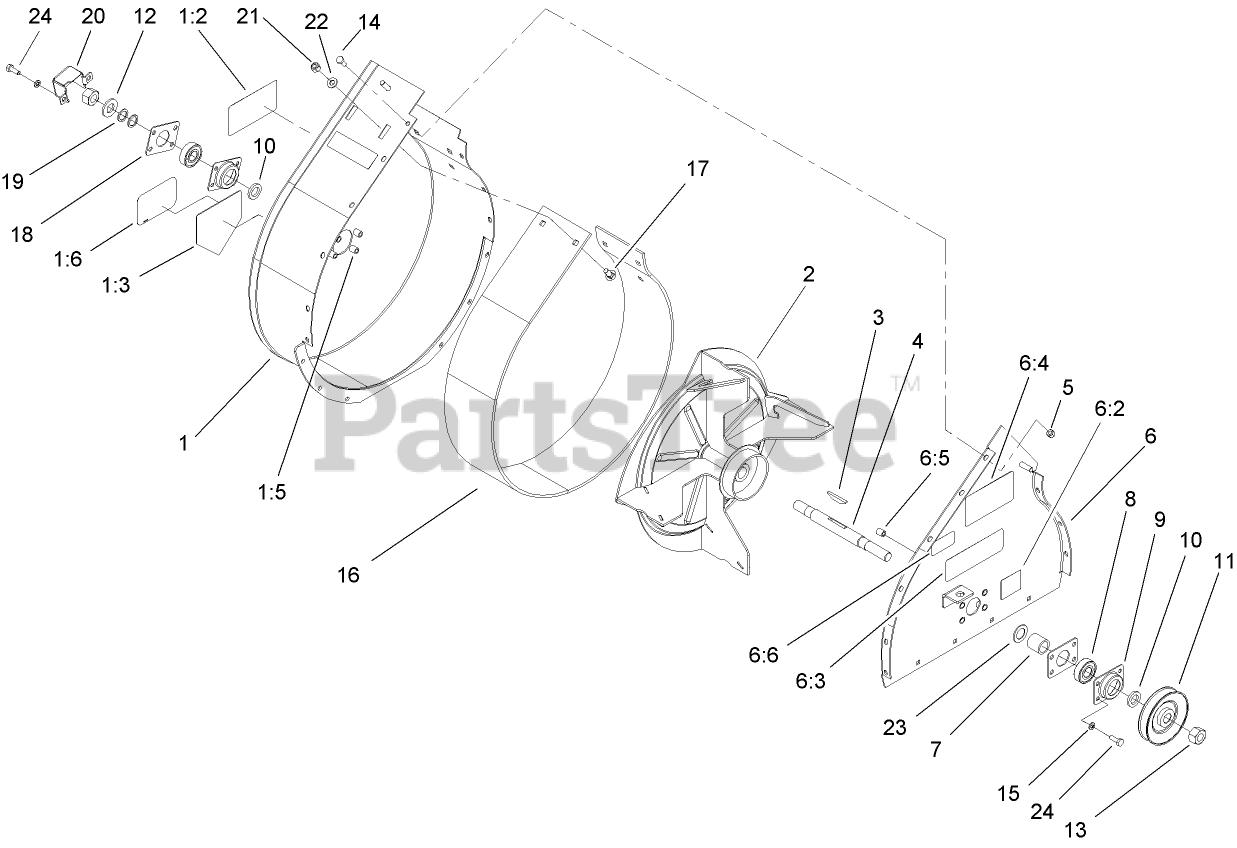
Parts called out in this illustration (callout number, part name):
1	BLOWER HOUSING ASM
1:2	DECAL-DANGER
1:3	DECAL-DANGER
1:5	INSERT-NUT
1:6	DECAL
2	IMPELLER ASM
4	Shaft-Blower
5	NUT-LOCK, NI
6	COVER PLATE ASM
6:2	DECAL-WARNING
6:3	DECAL-DANGER
6:4	DECAL-DANGER
6:5	INSERT-NUT
6:6	DECAL-PROTECTION, EAR
7	Spacer
8	BEARING-BALL
9	CUP-BEARING
10	SPACER-BEARING
11	Pulley ASM
12	WASHER-FLAT
13	NUT-HEX
14	SCREW-HH
15	WASHER-LOCK
16	STRIP-WEAR
17	BOLT-CARR
18	PLATE-COVER
19	WASHER-FLAT
20	Cover-Shaft
21	NUT-LOCK, NI
22	WASHER-PLAIN
23	WASHER-THRUST
24	SCREW-HH
